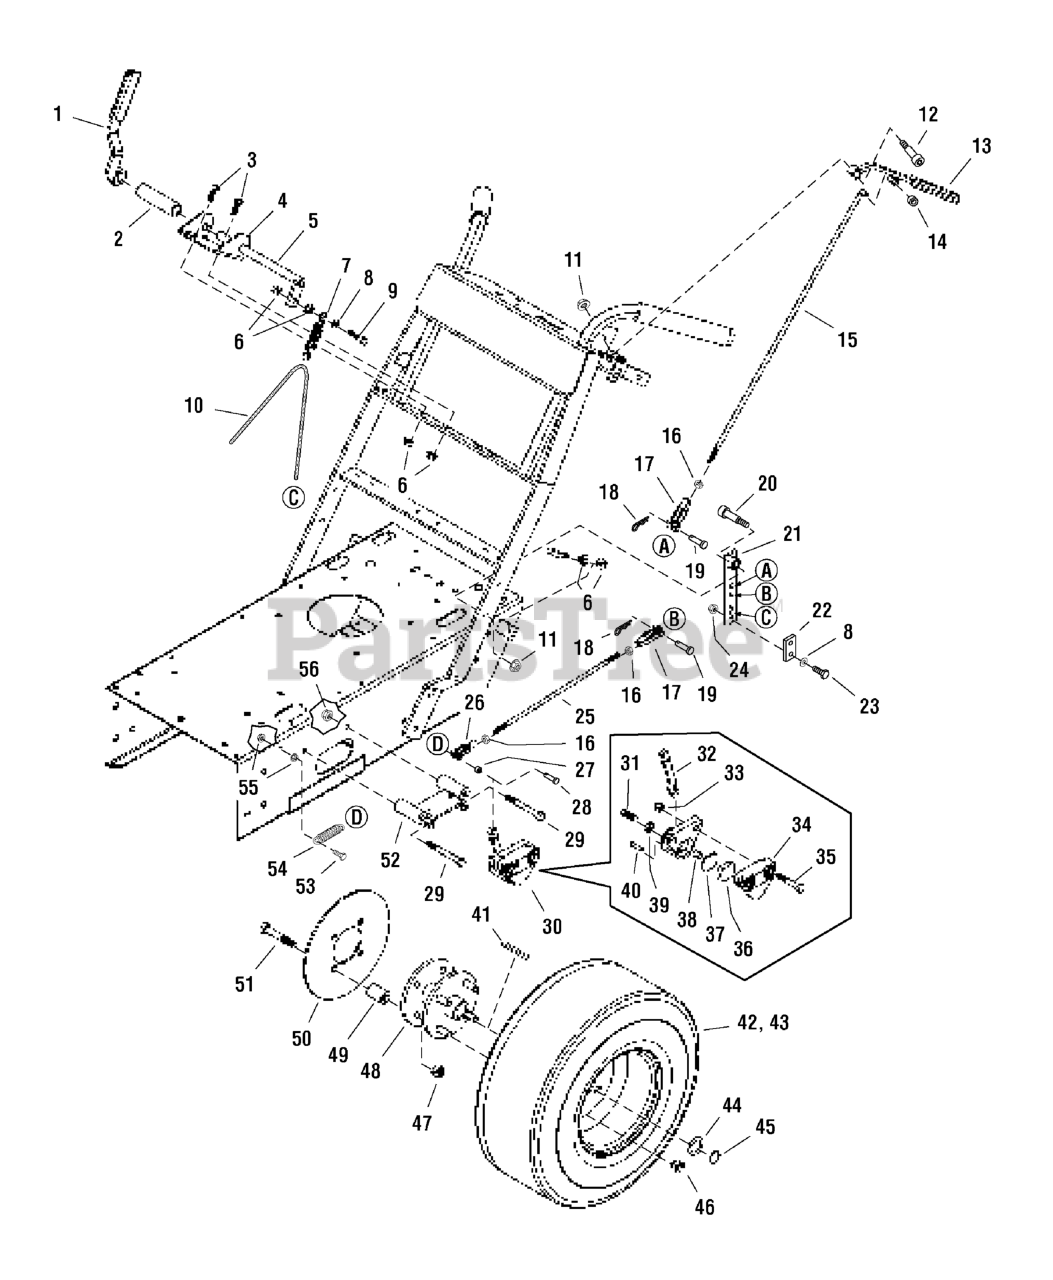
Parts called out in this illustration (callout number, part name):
1	PARKING BRAKE HANDLE
1	GRIP, FOAM, 1/4 X 1 X 4.1
2	COVER, Brake Rod
3	BOLT, 5/16-18 X 1 GD5 YZ
4	PARKING BRAKE MOUNT
5	PARKING BRAKE SHAFT
6	NUT, 5/16-18 HEX SERRATED FLANGE (LARGE)
7	SPRING, Extension
8	WASHER, 5/16" SAE
9	BOLT, 5/16-18 x 1-1/2
10	WIRE CABLE, 31-1/2
11	NUT, 3/8-16 Hex Serrated Flange
12	SHOULDER BOLT, 1/2 x 1-1/2
13	BRAKE HANDLE
13	GRIP, FOAM, 1/4 X 1 X 4.1
14	COLLAR, 5/16" Set
15	ROD, Brake Linkage
16	NUT, 5/16-24 Hex
17	CLEVIS, 5/16-24, Plastic
18	HAIRPIN CLIP
19	CLEVIS PIN, 5/16 x 1
20	SHOULDER BOLT, 1/2 x 1
21	BRAKE PIVOT
22	CABLE CLAMP
23	BOLT, 5/16-18 x 1-1/4
24	NUT, 5/16-18 Hex Nylon Lock
25	ROD, Linkage
26	CLEVIS, 5/16-24, Steel
27	SPACER, .25 X .37 X .25
28	PIN, CLEVIS, 1/4 X 7/8, PLATED
29	BOLT, 3/8-16 X 3-1/2" GD5 CZ
30	BRAKE CALIPER ASSEMBLY, LH, Complete
31	ADJUSTER BOLT
33	NUT, 3/8-16 HEX NYLON LOCK
35	BOLT, 3/8-16 X 2-1/4" GD5 CZ
36	BRAKE PAD
37	BACK PLATE
38	ACTUATOR PIN
39	JAM NUT
40	GROOVE PIN
41	KEY, 1/4 SQ. X 2-1/2
42	WHEEL & TIRE ASSEMBLY, 18 x 7.50 x 8, Silver
42	WHEEL, 6 x 8
42	TIRE, Rear, 18 x 7.5 x 8
43	TIRE ASSM, 16 x 6.50 x 8, Silver
43	Rim Only
43	TIRE, 16 x 6.5 x 8
45	RING, Retaining
46	LUG NUT, 1/2-20
47	NUT, Hex, Nylon Lock, 1/2-20
48	DRIVE HUB
49	BRAKE DISC SPACER
50	BRAKE DISC
51	BOLT, 1/2-20 x 3
52	BRAKE CALIPER MOUNT
53	BOLT, 1/4-20 X 1" GD5 CZ
54	SPRING, Extension
55	NUT, 1/4-20 HEX SERR. FLANGE
56	NUT, 1/2-13 HEX NYLON LOCK
